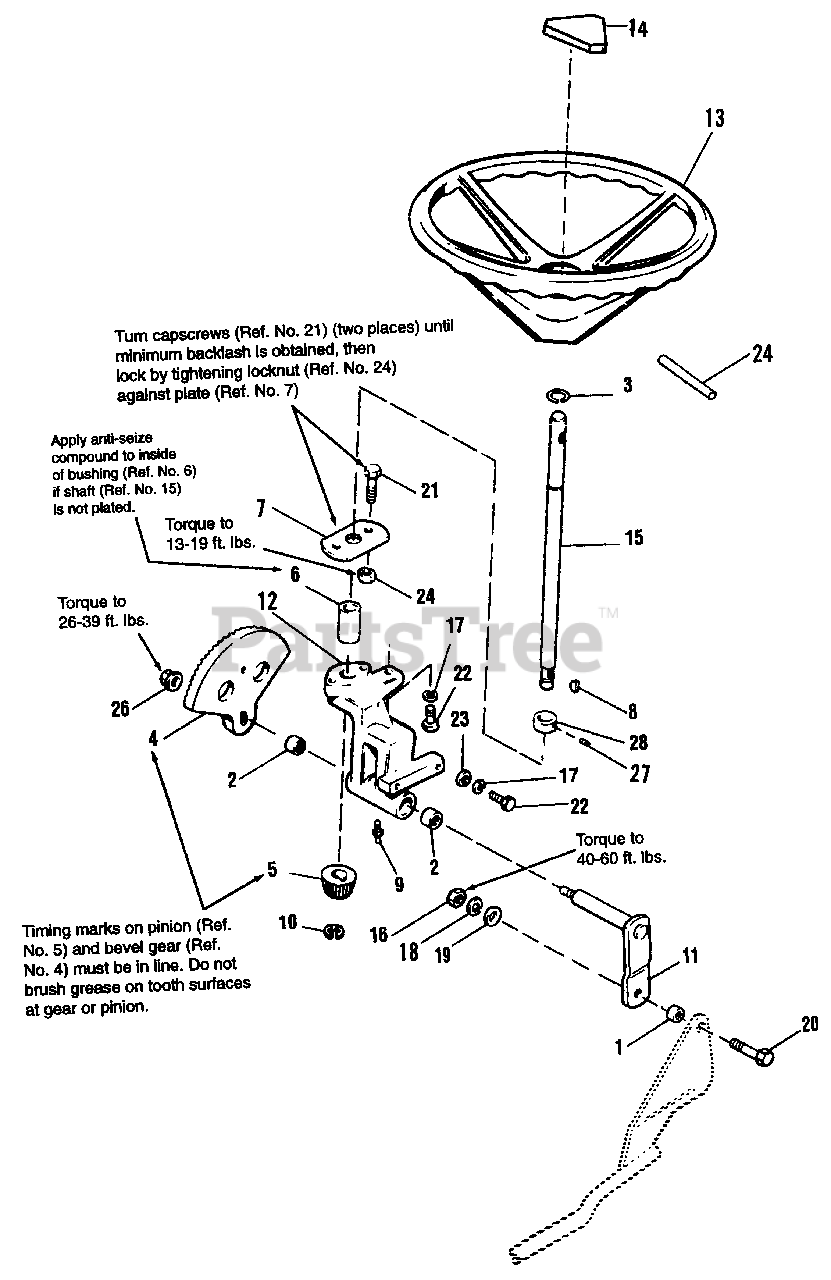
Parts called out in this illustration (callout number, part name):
2	BEARING, Needle
3	RING, Retaining
4	GEAR, Steering
5	PINION, Bevel
7	PLATE, Steering
8	KEY, Woodruff, #6
9	FITTING, Grease
10	E-RING
11	ARM ASSY., Steering
12	HOUSING ASSY., Steering (Incl. Ref. No. 22)
13	WHEEL, Steering (Incl. Ref. Nos. 14 & 27)
14	CAP, Steering Wheel
15	SHAFT, Steering
16	NUT, Hex, Full, 1/2-13
17	LOCKWASHER, 3/8
18	LOCKWASHER, 1/2
19	WASHER, Plain, 1/2
20	CAPSCREW, Hex Hd., 1/2-13 x 1-1/2
21	CAPSCREW, Hex Hd., 3/8-16 x 1-1/4
22	CAPSCREW,Hex Hd., 3/8-16 x 1/2
23	WASHER, Bevel, 3/8
24	LOCKNUT, Hex, Jam, 3/8-16
25	SETSCREW, 5/16-18 x 1/4
26	LOCKNUT, Hex, Flange, 7/16-14
27	PlN, Spring, 5/16 x 2
28	COLLAR, Set
